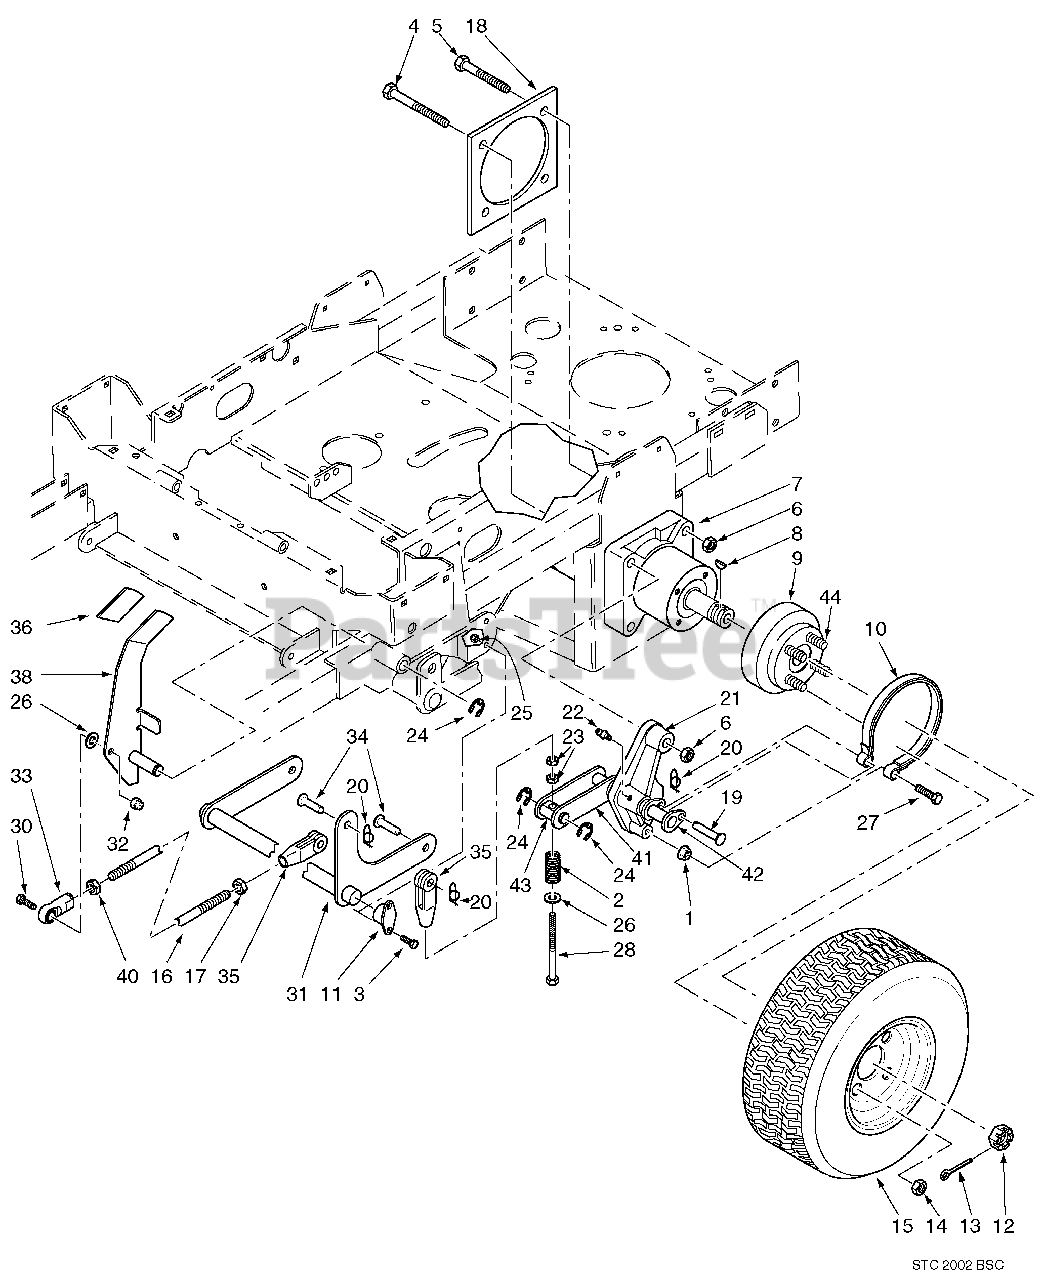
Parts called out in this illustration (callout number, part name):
1	Nut, Serr. Flange 3/8-16
2	Spring
3	Bolt, Hex Head 5/16-18 x 3/4"
4	Bolt, Hex Head 1/2-13 x 3-3/4"
5	Bolt, Hex Head 1/2-13 x 2-1/2"
6	Nut, 1/2-13 Center Lock
7	Wheel Motor, Hydro-Gear
8	Key, Woodruff 5/16 x 1"
9	Wheel Hub Assembly
10	Brake Band Assembly
11	Bushing, Self Align
12	Nut, Hex Castle 1.0-20 UNEF
13	Cotter Pin, 9/64 x 1-1/2"
14	Lug Nut, 1/2-20
15	Wheel Assembly 23 x 9.5 -12
15	Tire 23 x 9.5 - 12
16	Brake Rod Stud, 3/8-24 x 8.125
17	Nut, 3/8-24 UNF
18	Plate Weldment, Motor Backing
19	Clevis Pin, 3/8 x 1.93"
20	Pin, Rue Cotter 3/8 Dia.
21	Brake Linkage LH
21	Brake Linkage RH
22	Grease Fitting, 1/4-28
23	Nut, 3/8-24 UNF
24	Retaining Ring, .625 Ext.
25	Nut, Elastic Stop 5/16-18
26	Flatwasher, 3/8-.391 x .938 x .105
27	Bolt, Hex Head 3/8-16 x 2-1/2"
28	Bolt, Hex Head 3/8-24 x 3-3/4"
29	Cotter Pin, 3/32 x 3/4"
30	Bolt, Hex Head 3/8-16 x 1-1/2"
31	Brake Shaft
32	Nut, Elastic Stop 3/8-16
33	Rod End, 3/8-24 LH Thread
34	Clevis Pin, 3/8 x 1.06
35	Clevis, 3/8-24
36	Grip, Brake Lever
37	Nut, Serr. Flange 3/8-16
38	Brake Lever
39	Bolt, Hex Head 3/8-16 x 2-3/4"
40	Nut, 3/8-24 UNF-2B LH Thread
41	Lever, Brake
42	Shaft Weldment, Pivot
43	Pin, Pivot
44	Bolt, Serr. Flange 1/2-20 x 4.563"
